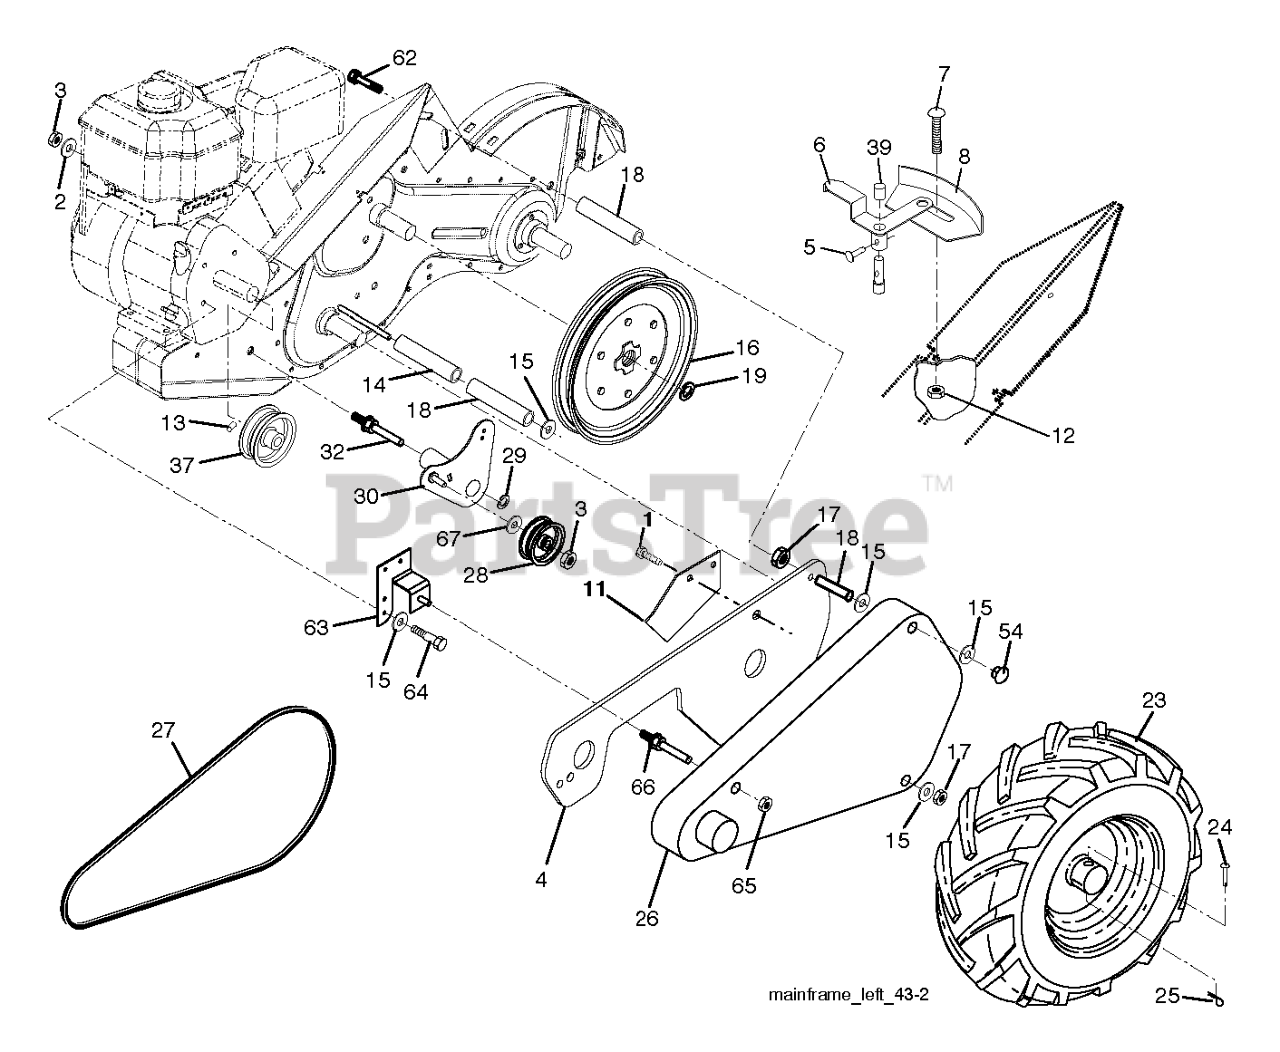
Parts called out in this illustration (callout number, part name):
1	SCREW.HEX.WASH.HD.TAPPING
2	SHIELD.SIDE.OUTER.LH.ORANGE
3	LOCKNUT
5	PIN.SPIROL.FLARED
6	LEVER ASM CRT
8	PANEL.INDICATOR.SHIFT.BLACK
11	GUARD.RT TILLER.21 HD.CE
12	NUT
14	SPACER-SPLIT.327 X .42
15	WASHER
16	SHEAVE, TRANSMISSION
18	SPACER SPLIT
19	RETAINING RING LT
23	WHEEL.DR.LH.16X4X8.TILLER.SILV
24	RIVET.PAN.HD.DRILLED
25	SPRING TI
26	GUARD.BELT.TILLER.8HP.ORANGE
27	BELT, DRIVE
28	PULLEY-IDLER TI
30	BRACKET.IDLER.ASM.SHORT
32	SHAFT, IDLER ARM
37	RPSHEAVE.3.50.TILLER.ZINC.SUBA
39	CAP.PLUNGER.BLACK
62	BOLT 5/16-18X4 1/2
63	BRACKET.ASM.GRD.BELT.INTEK.PNT
66	GUIDE.BELT.TILLER.HD.004
67	WASHER
